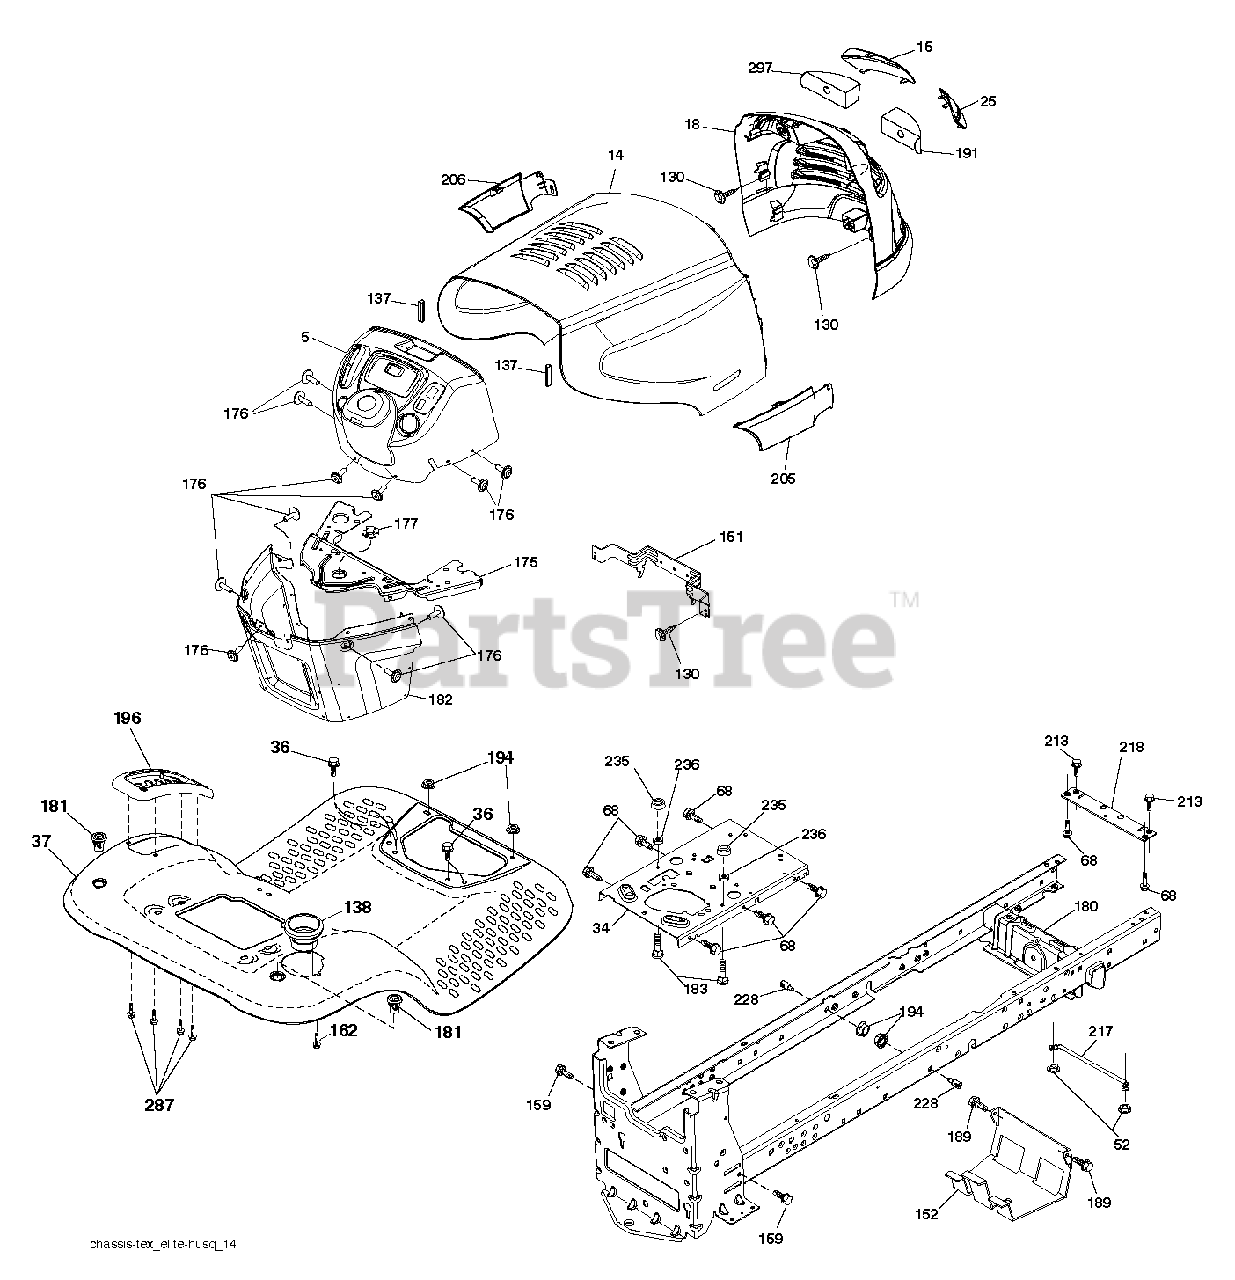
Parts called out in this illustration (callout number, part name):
5	DASH UPPER
14	HOOD.ELT.HUS/BSC.S/TP.SKT.421
18	GRILLE.ELITE HUSQ.BLACK.DL.
34	PLATE.ENGINE.WELDED.CHASSIS
36	SCREW 5/16"
37	FENDER.TLT.W/CPH.428
52	LOCKNUT
68	SCREW LT
130	SCREW.#10 X 0.750.BOS (2 2)
137	BUMPER.HOOD.LARGE.1.75"
138	CUPHOLDER.TL.TEX.BLACK
151	BRACKET PIVOT
152	SHIELD.BROWNING.W/TEX
159	SCREW, 3/8-16X3/4
162	SCREW.HI-LO.CONSOLE
175	CROSSMEMBER.LT
176	SCREW.#10-24X5/8.RN.QU
177	BUSHING,STEERING
180	CHASSIS
181	FEND/FTRST.PCH.CPH.NFW
182	DASH.LOWER.LT.CCS
183	BOLT.5/16-18X1-1/4 FULL THD
189	SCREW
191	INSERT LENS
194	NUT LOCK HEX FLANGE 5/16-18
213	BOLT
217	ROD.PIVOT.HOOD
218	X-PIECE.HOOD.STOP.NON/
228	STUD.FASTNER.W/ANTI-ROTATE
235	SPACER FENDER
236	NUT.CENTERLOCK.5/16-
287	SCREW 1/4X20
297	INSERT.REFLECTIVE.RH.
